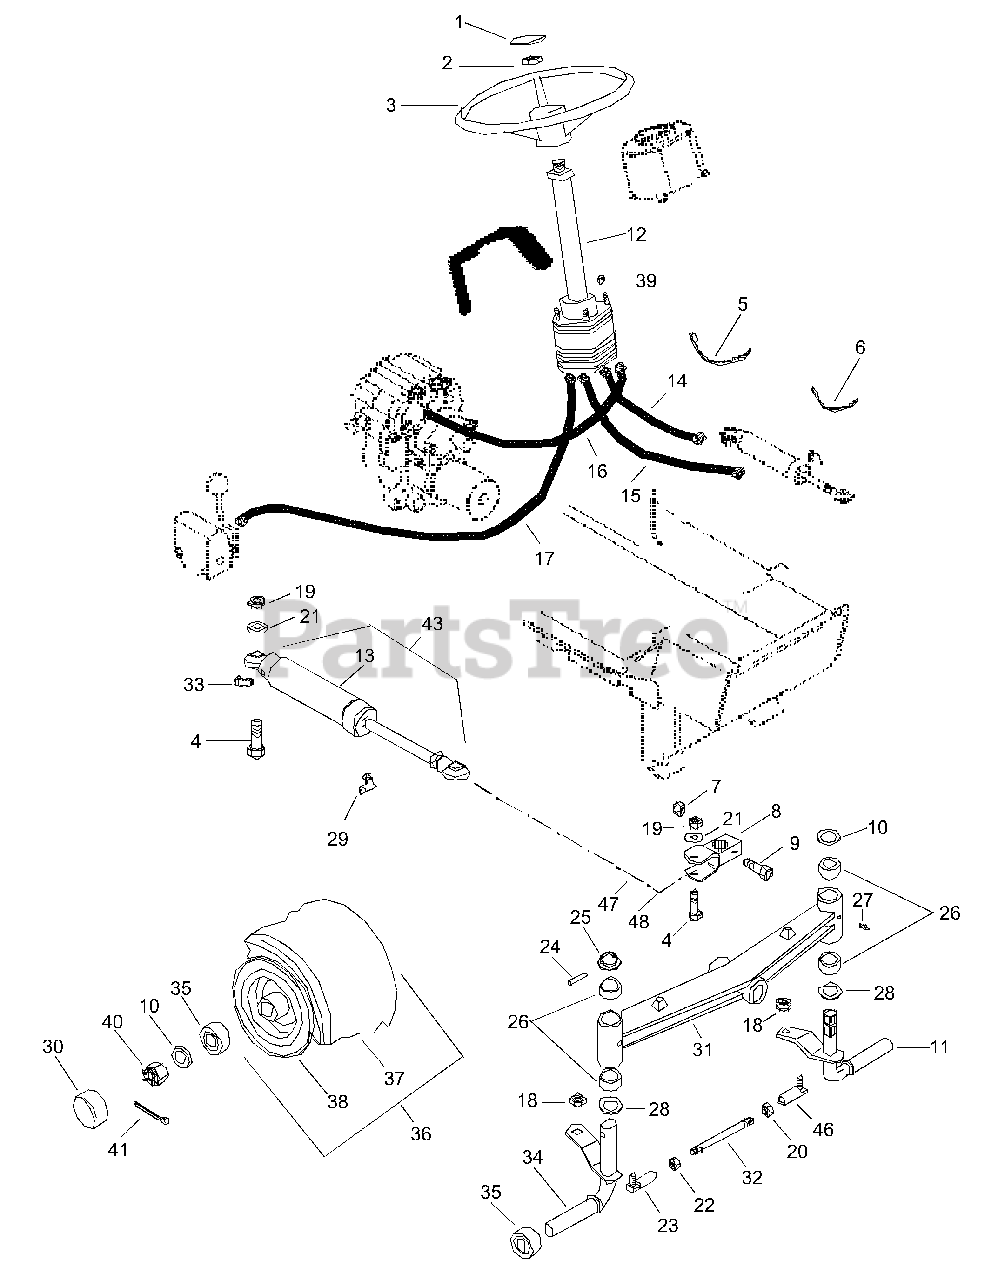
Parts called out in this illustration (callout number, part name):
1	Dome Plug
2	Nut-Locking-Jam .625-18
3	Steering Wheel
4	Bolt-Hex .62-18 x 2.00 Grade 5
5	Cable Tie
6	Tie Wrap
7	Nut-Locking .50-13
8	Steering Arm
9	Lock Bolt
10	Washer-Flat-Steel 1.010 x 1.505 x .062
11	Spindle Left Hand
12	Steering Unit-Hyd.
13	Cylinder-Hydraulic 2 Bore 3.87 STR.
14	Hydraulic Hose 31.5
15	Hydraulic Hose 35.75
16	Hose-Hydraulic
17	Hose-Hydraulic
18	Nut-Locking-Center .50-20
19	Nut-Locking-Jam .625-18
20	Nut-Jam-Left Hand .50-20 Grade 2
21	Washer-Flat-Steel .630 x 1.005 x .062
22	Nut-Lug .50-20
23	Ball Joint Right Hand
24	Pin-Roll .250 x 1.75
25	Spindle Cap
26	Bushing-Sleeve 1.000 x 1.125 x .875
27	Fitting-Lube .25-28 x .256
28	Plastic Washer
29	Adapter 45° 9/16 to 1/4
30	Front Hub Cap
31	Front Axle
32	Tie Rod
33	Adapter-90° .25 NPT x .56-18
34	Spindle Right Hand
35	Bearing-Ball 1.0 x 2.0 x .55
36	Tire/Wheel Assembly
37	Tire 8 x 6.50
38	Wheel
39	Nut-Locking-Center .31-24
40	Nut-Slotted 1.0 - 14
41	Pin-Cotter .18 x 1.25
42	Ball Joint Left Hand
43	Cylinder Assembly (Short)
44	Front Axle Assembly
